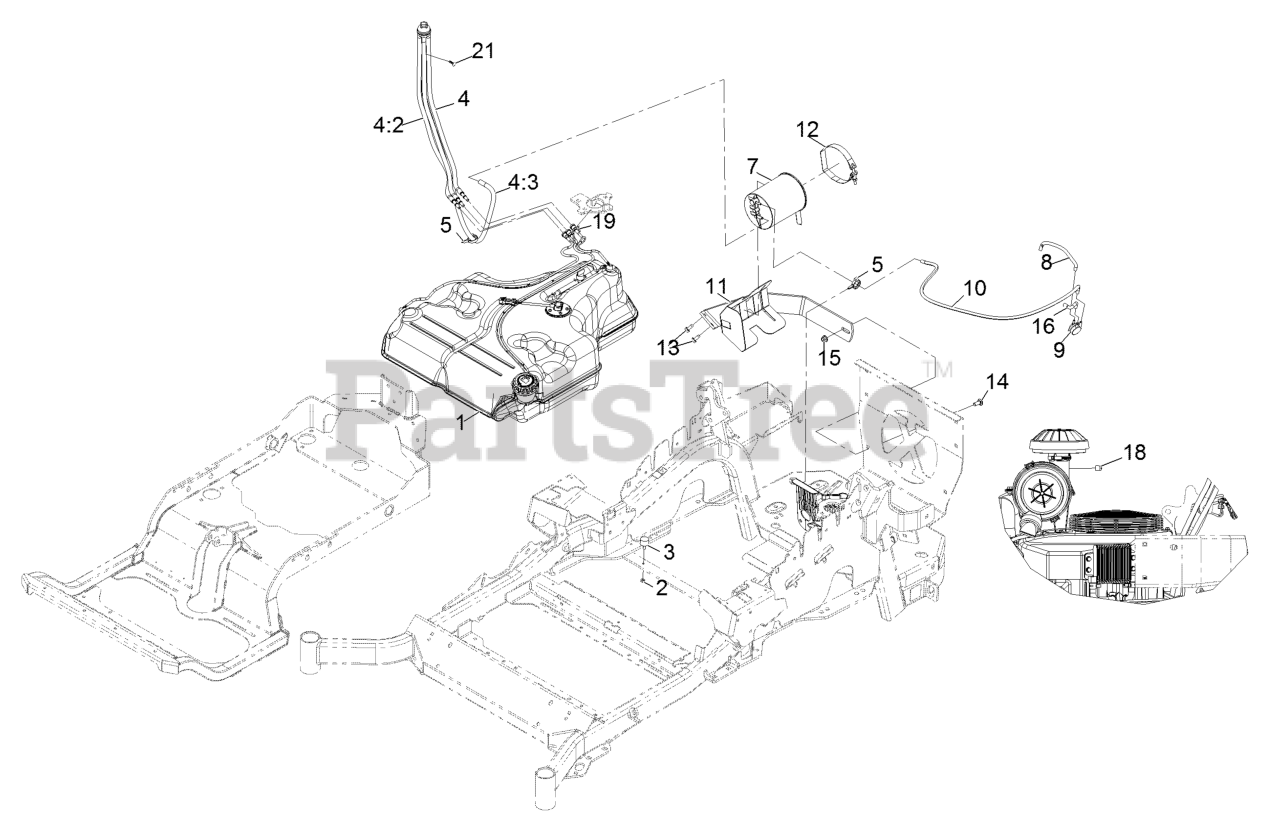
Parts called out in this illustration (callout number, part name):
1	Fuel Tank ASM
2	Nut-Jam 1/4-20
4	Fuel Manifold Vent ASM
4:2	Hose-Fuel Line 24"
4:3	Hose-Fuel
5	Clamp-Hose
7	Canister-Carbon, 1200Cc
8	Hose-Vent,Formed
9	Valve-Control, Vacuum
10	Hose,Vent,Formed
11	Mount-Canister
12	Clamp, T-Bolt
13	Screw-HWH 5/16-18 X 3/4 Tf
14	Bolt-Carriage 3/8-16 X 1
15	Nut-Nyloc 3/8-16 Flg
16	Hose-Vent, Formed
18	Plug-Port
19	Retainer-Line, Vapor
21	Plug-Plastic
